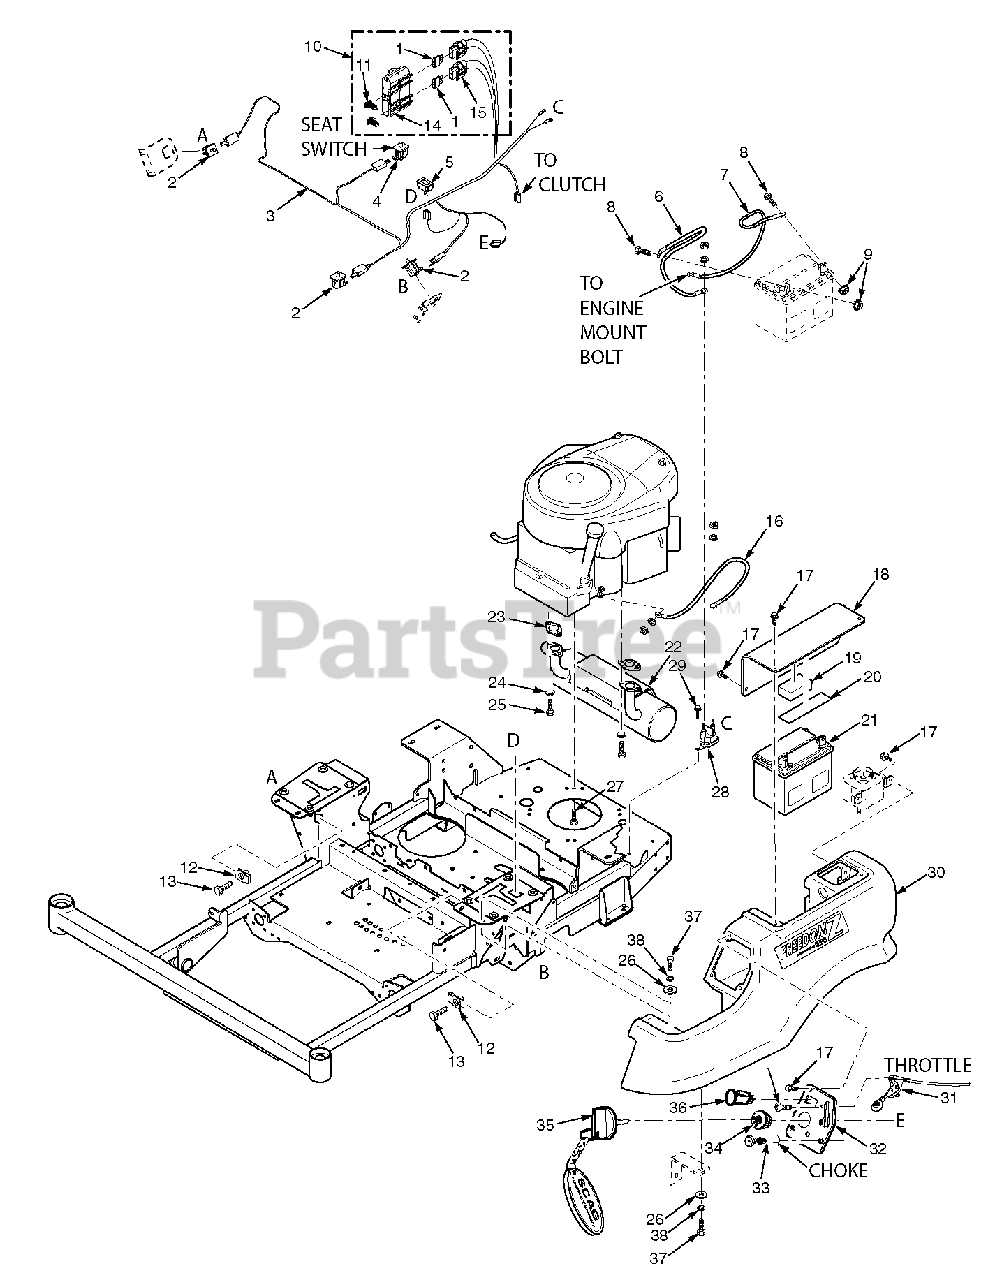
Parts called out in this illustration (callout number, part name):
1	Fuse, 20 amp
2	Switch
3	Wire Harness, Main
4	Switch, Seat
5	Hourmeter
6	Battery Cable, Red 25"
7	Battery Cable, Black 27"
8	Bolt, Hex Head 1/4-20 x 1/2"
9	Nut, 1/4-20
10	Double Fuse Assy.
11	Clip, Wire
12	U-Nut, 3/8-16
13	Bolt, Hex Head 3/8-16 x 1-1/4" Special Lock
14	Cover, Sealed Double
15	Fuse Holder
16	Battery Cable, Red 9"
17	Bolt, Hex Head 1/4-20 x 1/2" Serr. Flange
18	Battery Cover
19	Pad, Battery Hold Down
20	Rubber Pad
21	Battery (not avail. through Scag)
22	Muffler, Briggs & Stratton
22	Muffler, Kawasaki FS
23	Exhaust Gasket
24	Lockwasher
25	Bolt
26	Flatwasher, 5/16-.375 x .875 x .083
27	Bolt, Hex Head 3/8-16 x 1-1/4" (Kawasaki)
27	Lockwasher, 3/8" Spring (Kawasaki)
27	Bolt, Hex Head 5/16-18 x 1-1/2" (Briggs)
27	Nut, 5/16-18 Serrated Flange
27	Lockwasher, 5/16" Spring (Briggs)
27	Capscrew, Hex Head 3/8-16 x 1-1/4" Self Tap Briggs)
28	Solenoid
29	Bolt, Self Tapping 1/2-20 x 3/4" Shakeproof
30	Tank, LH
31	Throttle Cable
32	Instrument Panel w/Decal
33	Choke Cable, Briggs & Stratton
34	Ignition Switch
35	Key, Ignition
35	Key w/Shroud
35	Key Assembly w/Fob
36	PTO Switch
37	Bolt, Hex Head 5/16-18 x 3/4"
38	Lockwasher, 5/16" Spring
